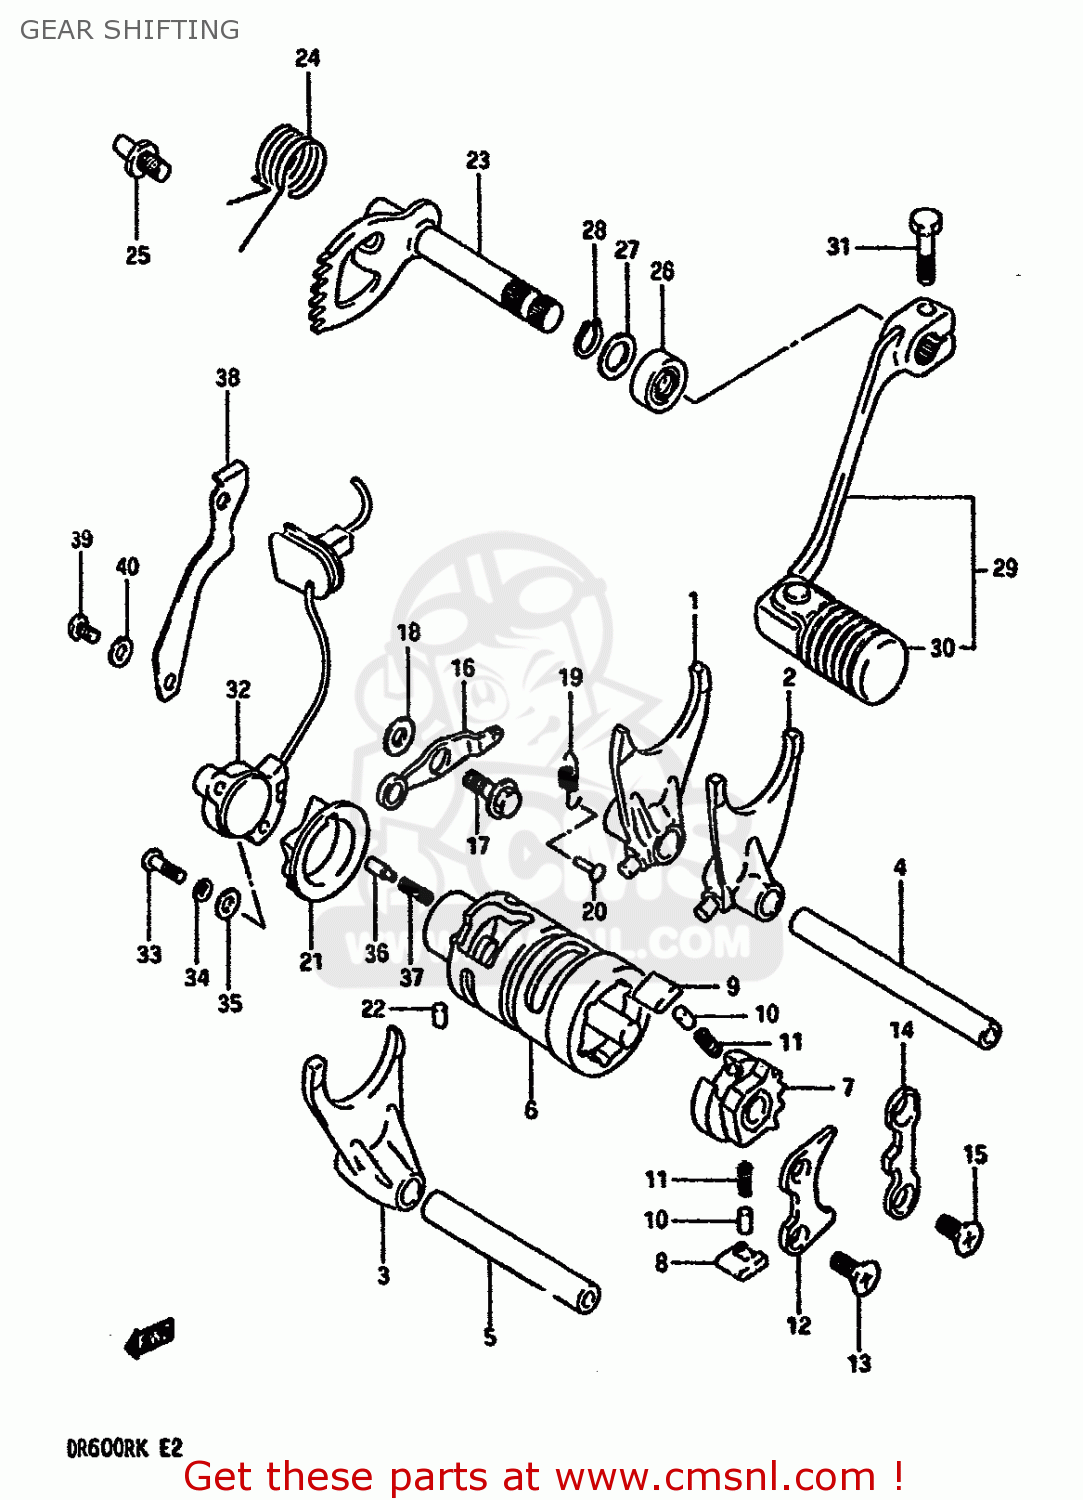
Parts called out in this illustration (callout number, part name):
1	FORK,GEAR SHIFT NO.1
2	FORK,GEAR SHIFT NO.2
3	FORK,GEAR SHIFT NO.3
4	SHAFT,GEAR SHIFT FORK
5	SHAFT,GEAR SHIFT FORK
6	CAM,GEAR SHIFT
7	GEAR,GEARSHIFT CAM DRIVE
8	PAWL,GEAR SHIFT NO.1
9	PAWL,GEAR SHIFT NO.2
10	PIN(5X8)
11	SPRING
12	LIFTER,GEAR SHAFT PAWL
13	SCREW
14	STOPPER,GEAR SHIFT POLE
15	SCREW
16	STOPPER,GEAR SHIFT CAM
17	BOLT
18	WASHER
19	SPRING
20	RIVET
21	PLATE,SHIFT CAM STOPPER
22	PIN 4X6
23	SHAFT,GEAR SHIFT
24	SPRING
25	STOPPER,GEAR SHIFT CAM
26	OIL SEAL
27	WASHER
28	CIRCLIP
29	LEVER ASSEMBLY,GEAR SHIFTING
30	RUBBER,GEAR SHIFT PEDAL
31	BOLT
32	TERMINAL BASE,NEUTRAL
33	SCREW
34	LOCK WASHER
35	WASHER
36	PIN(5X15.5)
37	SPRING
38	CLAMP,LEAD WIRE
39	SCREW
40	WASHER,LOCK
